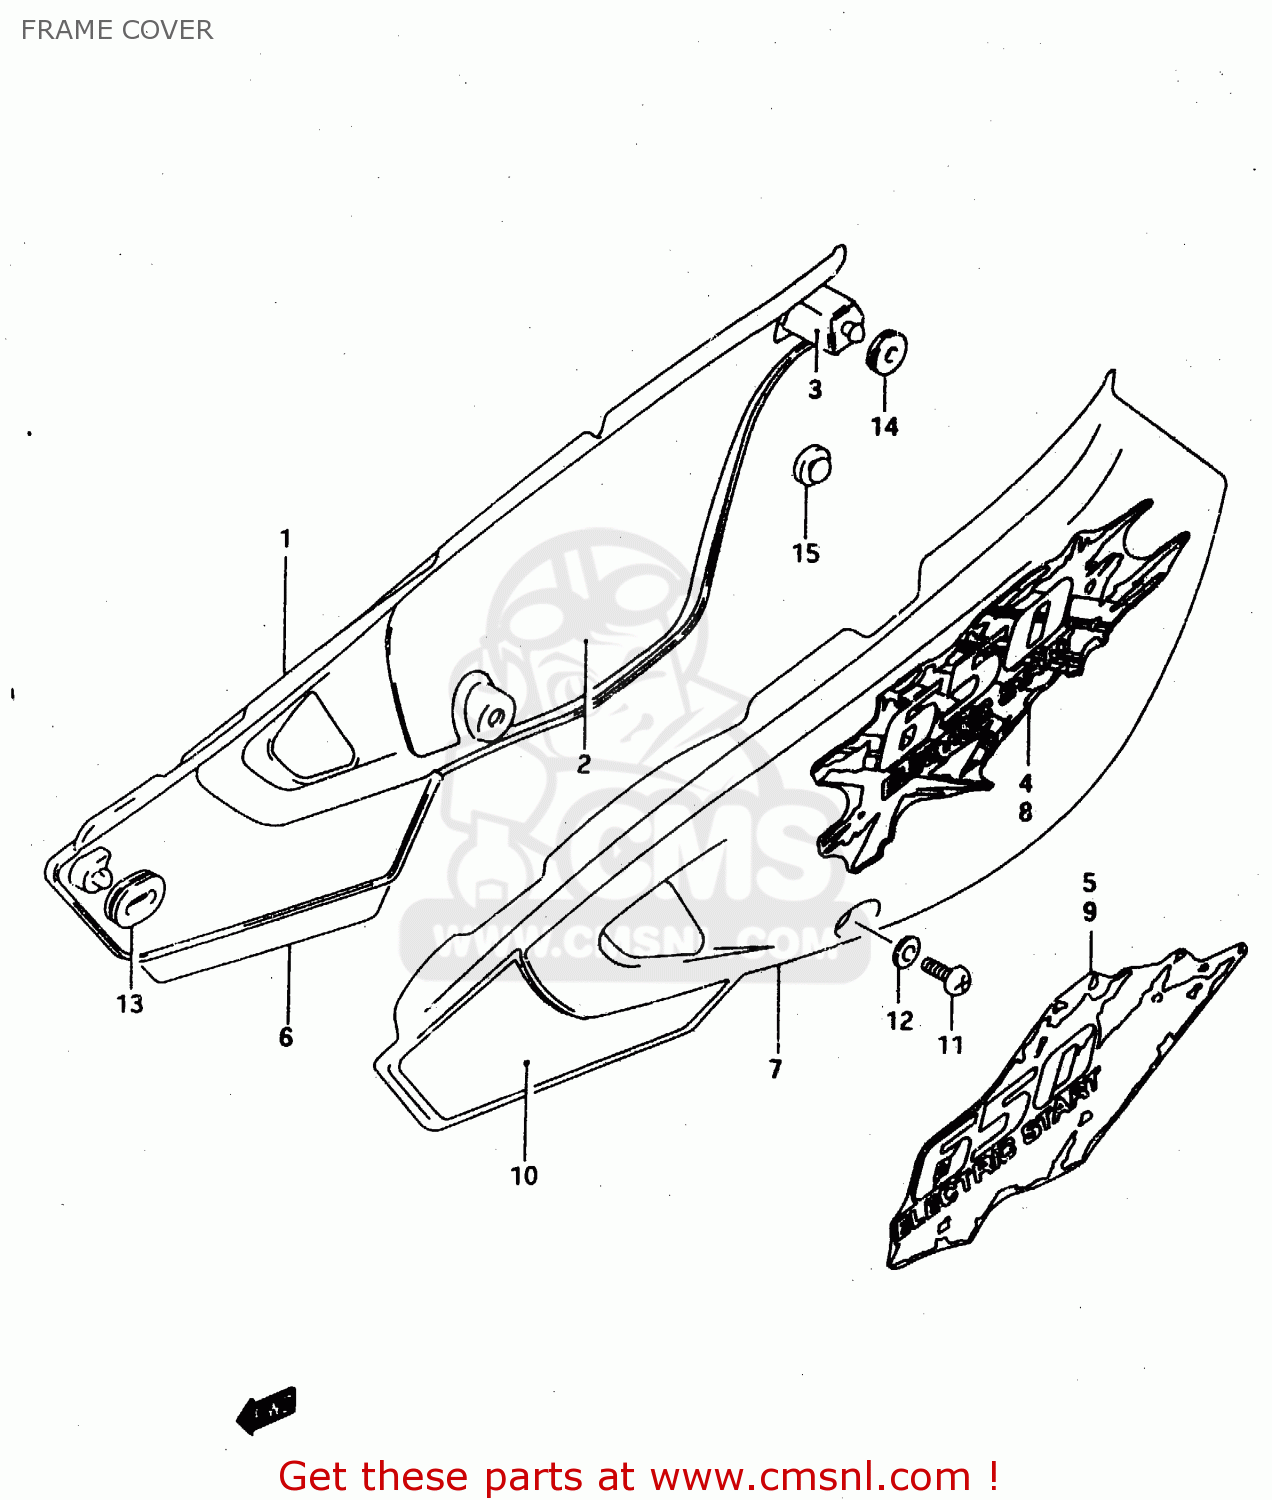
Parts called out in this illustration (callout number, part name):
1	COVER,FRAME,RIGHT
2	SHIELD,FRAME COVER,R
3	SHIELD,FRAME COVER,R NO.2
4	TAPE, LH
5	TAPE,FRAME COVER,RIGHT
6	TAPE,FRAME COVER NO.2
7	COVER,FRAME,L(WHITE)
8	TAPE, LH
9	TAPE,FRAME COVER,LEFT
10	TAPE,FRAME COVER NO.2
11	SCREW
12	WASHER
13	CUSHION
14	CUSHION
15	CUSHION
